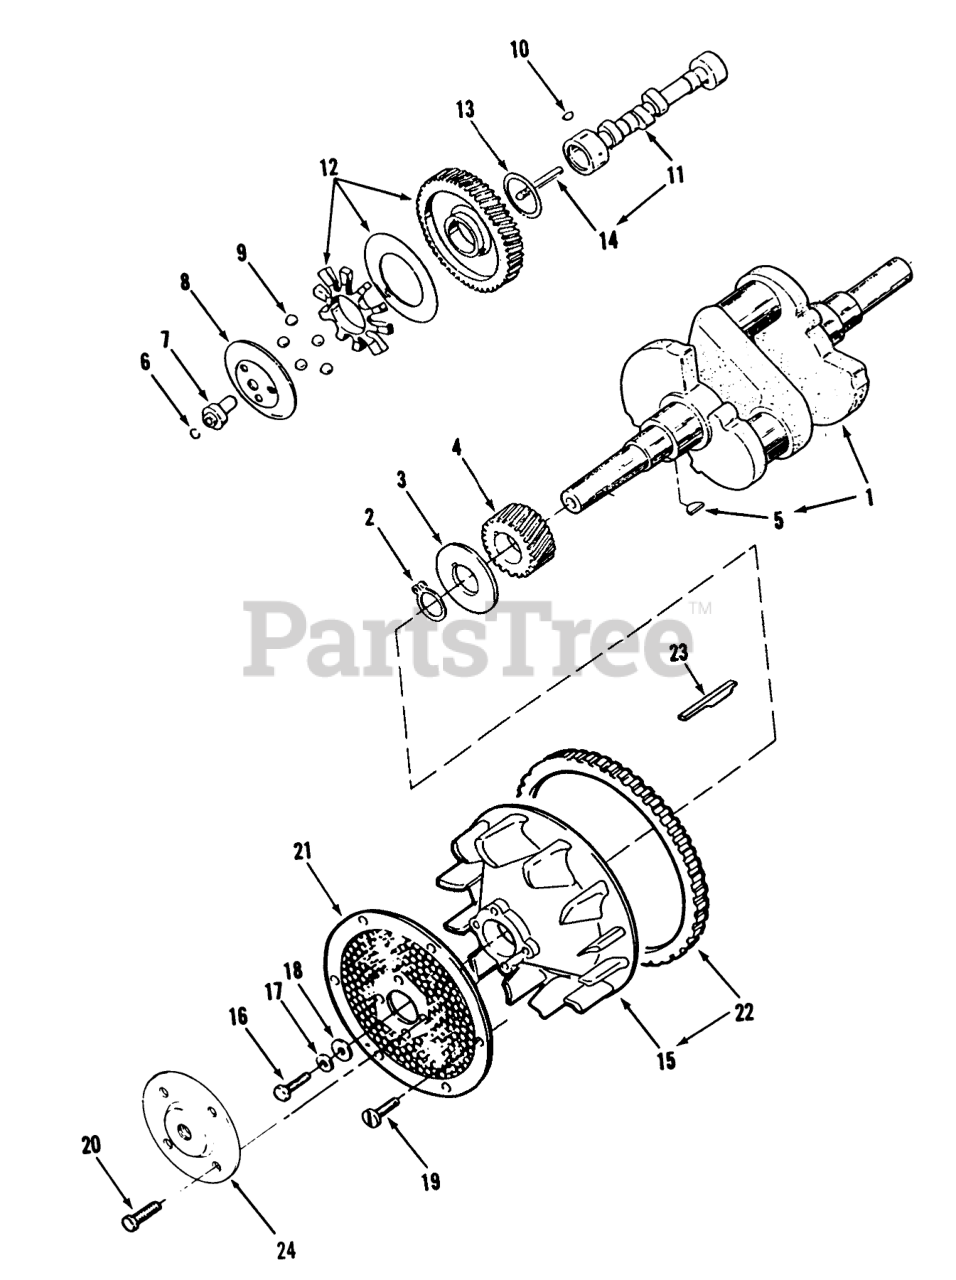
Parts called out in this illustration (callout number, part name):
1	CRANKSHAFT
3	WASHER
7	HUB-GOVERNOR CUP
8	CUP-GOVERNOR
9	BEARING
11	CAMSHAFT (16&18HP)
12	GEAR ASM
13	WASHER-THRUST
14	PIN-CENTER
15	Flywheel-w/Ring Gear
16	SCREW
17	Washer
18	WASHER-FLAT
19	Bolt
20	HX HD LOCK CAPSCREW
21	Screen
23	Key
24	LIFTING-BRKT (ZINC)
